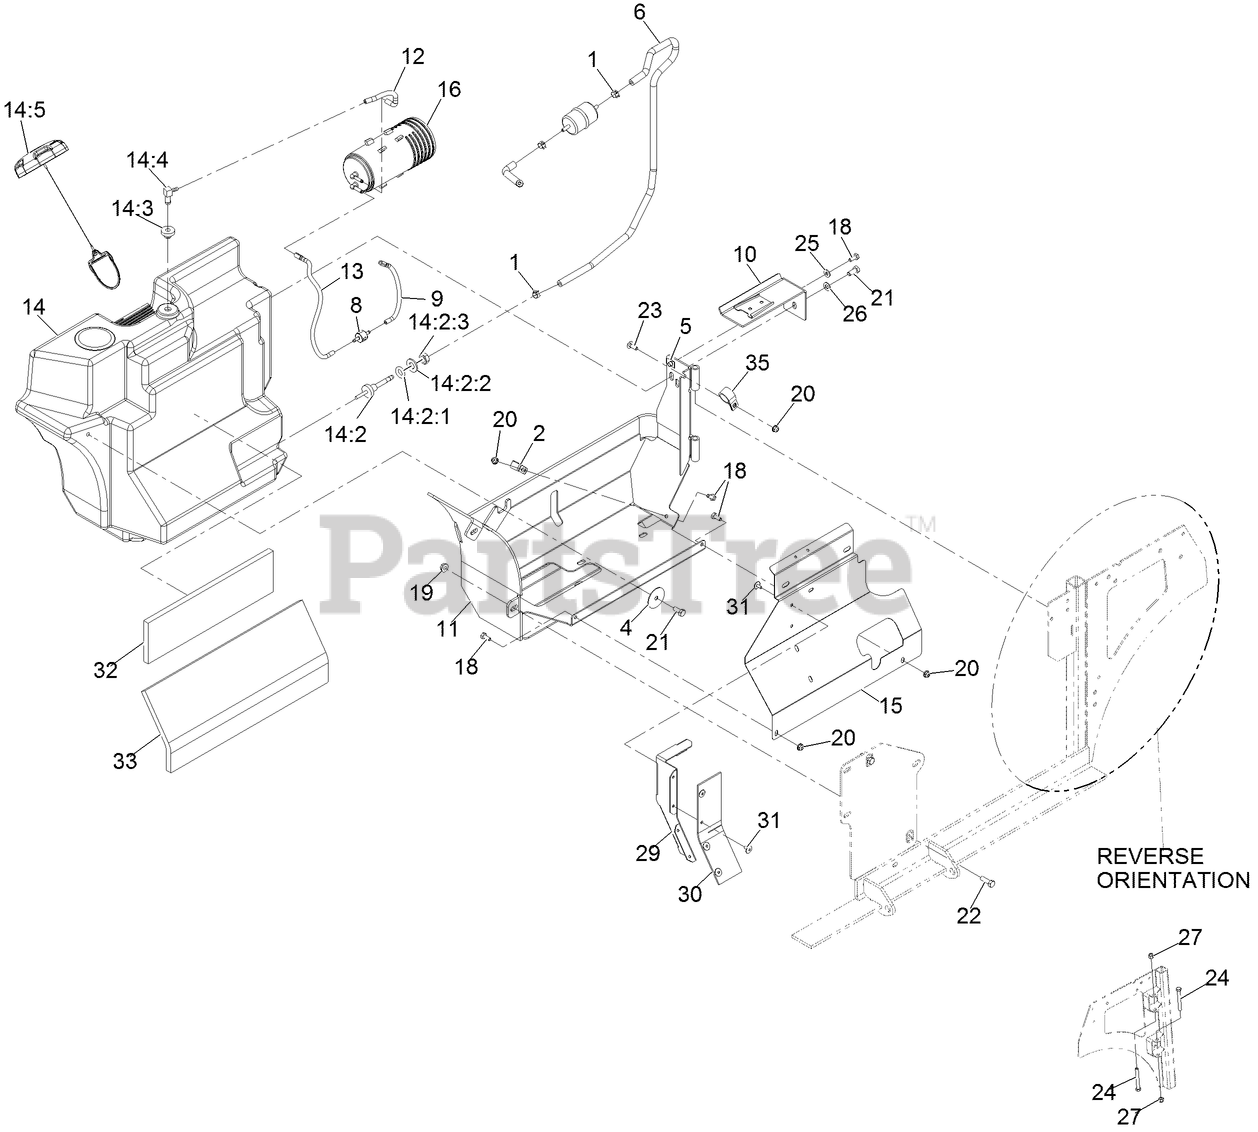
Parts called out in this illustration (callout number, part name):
1	CLAMP-HOSE
2	CLIP-LOOM
4	WASHER
6	FUEL LINE ASM
8	VALVE-CHECK, VACUUM
9	HOSE-VENT, FORMED
10	CANISTER BRACKET ASM
11	TANK FRAME ASM
12	HOSE-VENT, FORMED
13	HOSE-VENT, FORMED
14	FUEL TANK ASM
14:2	FITTING-FUEL, BULKHEAD
14:2:1	O-RING,BULKHEAD FITTING
14:2:2	WASHER-FLAT
14:2:3	NUT-JAM
14:3	BUSHING
14:5	CAP-FUEL, RATCHETING
15	PANEL-TANK SHIELD
16	CANISTER-CARBON, 800CC
18	SCREW-HH
19	NUT-HF
20	NUT-HF
21	SCREW-HH
22	SCREW-HH
23	BOLT-CARR
24	SCREW-HH
25	WASHER-FLAT
26	WASHER-PLAIN
27	NUT-LOCK, NI
29	DEFLECTOR-AIR
30	FLAP-RUBBER
31	RIVET-POP
32	INSULATION-FOAM PAD, FRONT
33	INSULATION-FOAM PAD, REAR
35	R-CLAMP
